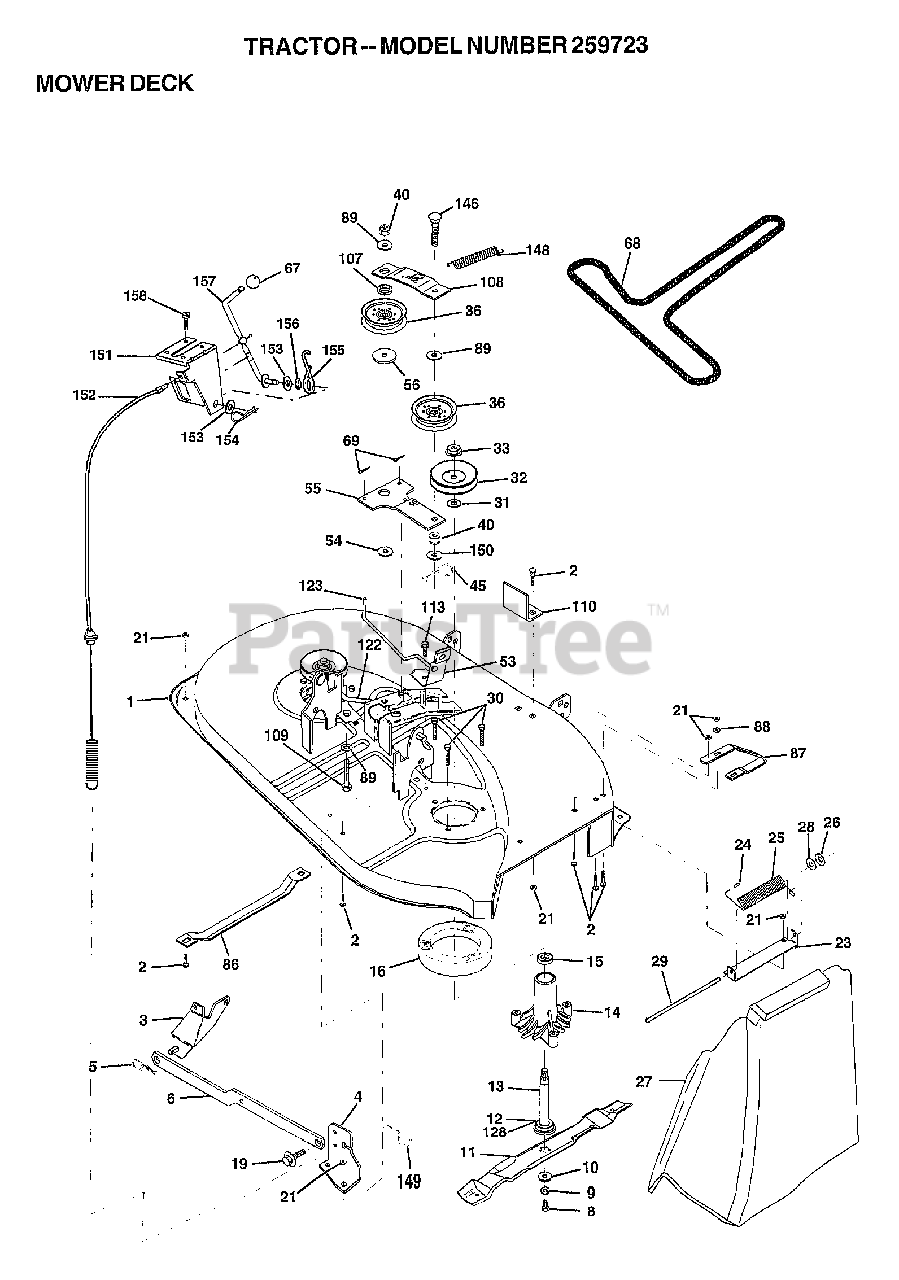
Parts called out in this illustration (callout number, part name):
1	MOWER HSG ASSY
2	BOLT
3	BRKT ASM SWAY BAR
4	BRKT SWAY BAR DECK
8	BLADE BOLT
10	WASHER.HARD.BLADE
11	"BLADE.38"" HIPERF"
12	BEARING.BALL
14	HSG ASM MANDREL
15	BEARING
16	STRIPPER RND MWR
19	BOLT SHD 5/16-18
23	BRKT DEFLECTOR
24	CAP-SLEEVE LT
25	SPRING TORSION
26	NUT PUSH M
27	DEFLECTOR, SHIELD
28	WASHER
29	ROD-HINGE T
30	"SCREW-THD ROLL,WA"
31	WASHER
32	PULLEY.MANDREL.38
36	FLAT IDLER PULLEY
45	RETAINER M
53	BRAKE ASM
54	HARDENED WASHER
55	IDLER ARM ASSY
56	SPACER.RETAINER.MOWER
67	KNOB T(3/8 HOLE)
68	BELT.V.T-PATH
86	RUNNER-LH M
87	RUNNER RH
88	WASHER M
89	WASHER GT
107	RETAINER SPACER
108	IDLER ARM STIFF
109	BOLT
110	UPSTOP DECK FT 38
113	SCREW
122	BRAKE ROD LH
123	ROD
128	WASHER.FELT.
146	BOLT
148	SPRING RETURN IDLER
149	RETAINER SPRING
150	WASHER PM
151	BRKT CLUTCH CABLE
152	CLUTCH CABLE
153	WASHER FLAT
154	SPRING RETAINER
155	SPRING RETENTION LVR CLUTCH CAB
156	SPACER
157	ROD.CLUTCH.CABLE.3/8
158	SCREW LT
